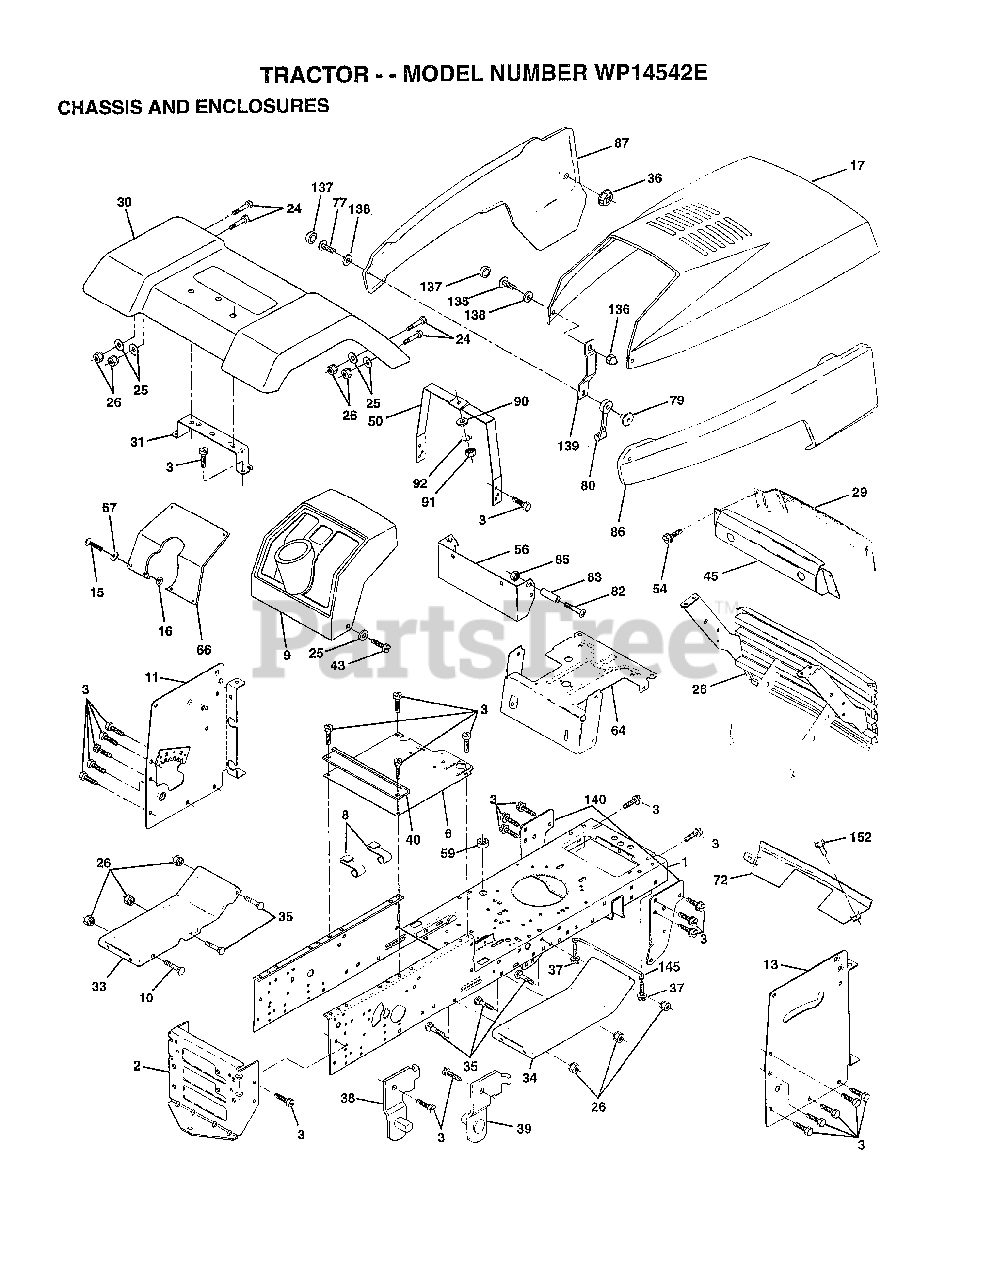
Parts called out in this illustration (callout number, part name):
3	SCREW
6	SADDLE
8	"CLIP,INSULATOR"
9	DASHBOARD BLACK
11	PANEL.DASH.LH.
13	PANEL.DASH.RH.
15	SCREW
24	BOLT
25	WASHER
26	NUT
28	GRILLE ASM PNT
29	LENS.BAR.CLEAR
30	FENDER.PNT.ASSY
31	BRACKET SUPT FEND
33	FOOTREST.LH.LT/GT
34	FOOTREST.RH.LT/GT
35	BOLT
36	PAL NUT LT
38	BRACKET ASM LH
39	BRACKET ASM RH
40	SPACER FENDER LT
43	SCREW GTV
45	BEZEL.ASM.
50	DASH.SUPT.YP/HUSQ
54	SCREW.HEX.WS.HD
56	EXT DASH LTYT
64	DASH.LOWER.LT
66	"PLATE-DASH,SLSCR"
67	WASHER
72	STRAP.GRILLE.PNT.
77	SCREW
79	WELDNUT
80	HOOD LATCH T
82	SCREW
83	SPACER LT
87	"PANEL SIDE,LH"
90	WASHER PM
92	LOCKWASHER
135	SCREW.10-24X3/8.
136	ACORN NUT RB
137	SNAP CAP LT
138	WASHER LT
139	BKT.SPT.HOOD/PANL
140	BRKT SUSPENSION
145	"ROD POVOT,CHASSIS"
152	SCREW
